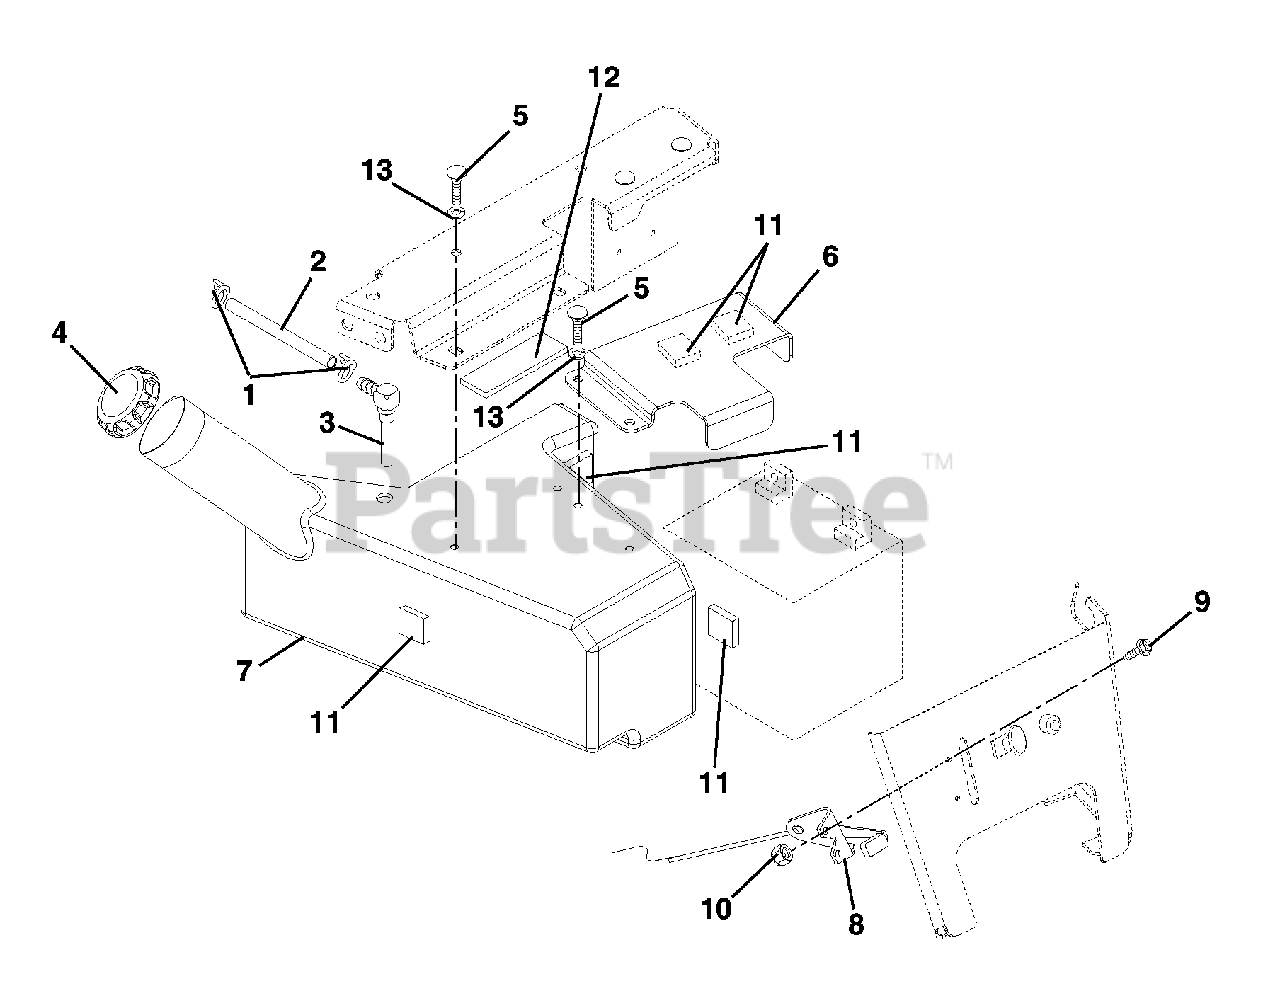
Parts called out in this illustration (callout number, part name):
1	Clamp, Hose Wire .490/.510 x .116
2	Gas Line, Bulk 1/4" I.D.
3	Fitting, Tank
4	Fuel Cap
5	Bolt, Serrated Hex Flange Washer Head .25-20 x .75
6	Bracket, Battery
7	Tank, Fuel
8	Cable, Throttle
9	Screw, Machine 10-24 x .50 Hex Washer Head
10	Nut, Locking Nylon 10-24 with Insert
11	Pad, Foam
12	VHB Tape 4941F
13	Washer, Locking .31 x .078 Regular
